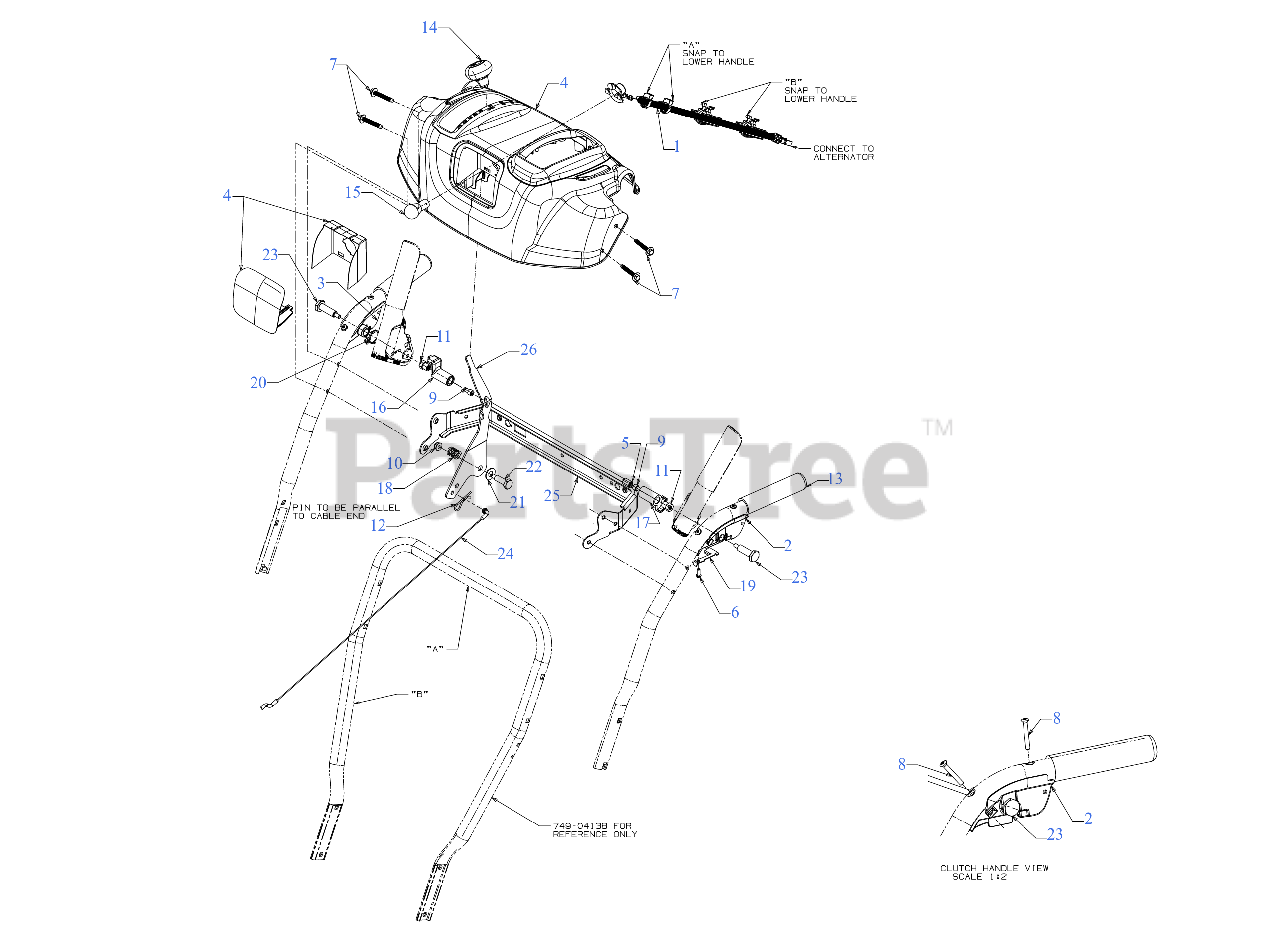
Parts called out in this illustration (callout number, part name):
1	HEADLIGHT SOCKET
1	LIGHT HARNESS
2	CLUTCH LOCK HANDLE ASSEMBLY (LH)
3	CLUTCH LOCK HANDLE ASSEMBLY (RH)
4	HANDLE PANEL ASSEMBLY
5	PIVOT ROD
6	SCREW #8-16 x .50
7	SCREW 1/4-20 x 1.625
8	SCREW #10-24 x 1.375
9	SCREW 1/4-20 x .50
10	FLANGE LOCK NUT
11	HEX NUT W/PATCH
12	INTERNAL COTTER PIN
14	SHIFT KNOB
15	LAMP-12 VOLT
16	LOCK PLATE
17	CLUTCH LOCK CAM
18	COMPRESSION SPRING
19	CLUTCH SPRING
20	TORSION SPRING
21	FLAT WASHER .40X.88X.060
22	SHOULDER SCREW
23	SHOULDER SCREW .437 x 1.345 1/4-20
24	SPEED SELECTOR CABLE (PLASTIC)
25	HANDLE SUPPORT BRACKET (POWDER BLACK)
26	SHIFT LEVER
